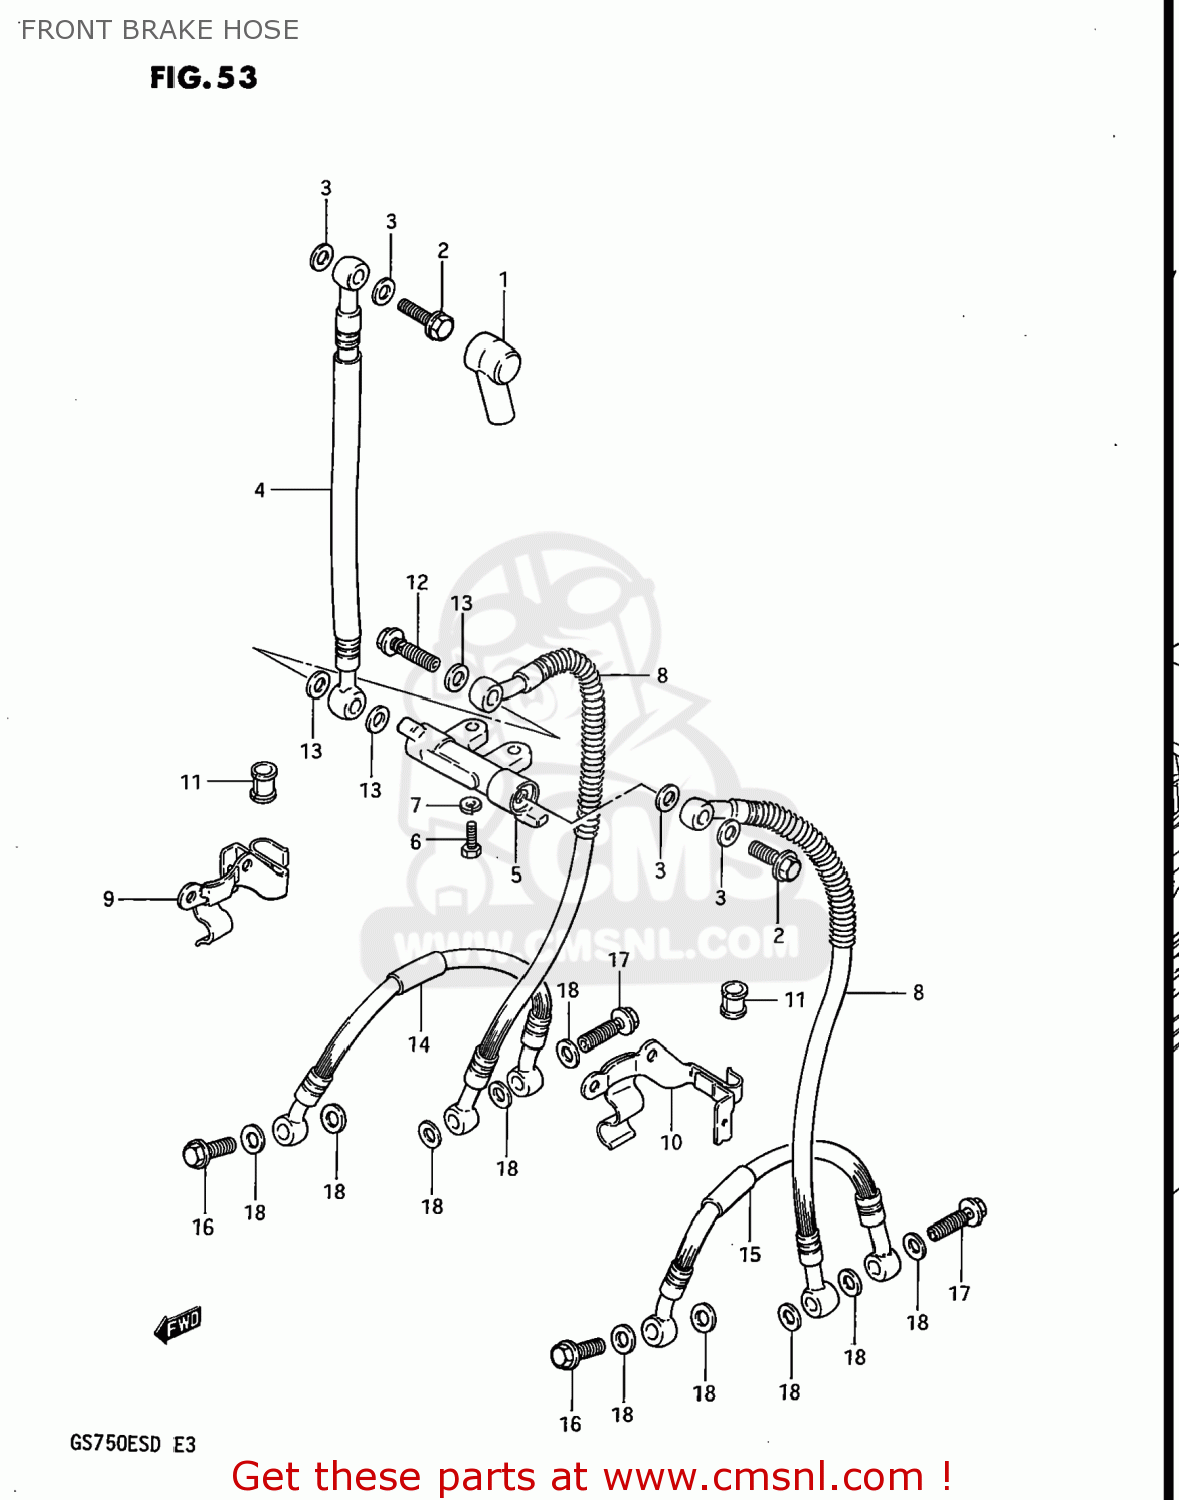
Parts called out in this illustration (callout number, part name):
1	BOOT
2	BOLT UNION
3	WASHER
4	HOSE,FRONT BRAKE
5	JOINT,BRAKE HOSE
6	BOLT
7	LOCK WASHER
8	HOSE,FRONT BRAKE NO.2
9	CLAMP,FRONT BRAKE HOSE
10	CLAMP,BRAKE HOSE,LEFT
11	BUSH,BRAKE HOSE GUIDE,NO.2
12	BOLT,UNION
13	WASHER
14	HOSE,ANTI-NOSE DIVE
15	HOSE,ANTI-NOSE DIVE
16	BOLT UNION
17	BOLT,UNION
18	WASHER
